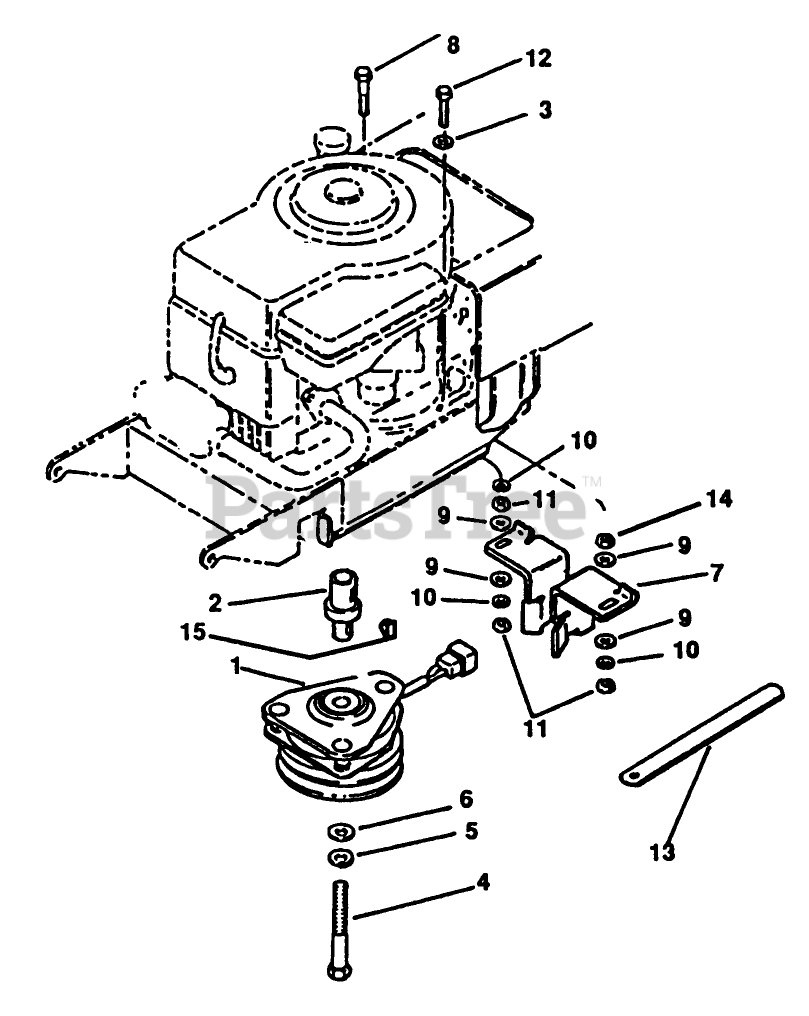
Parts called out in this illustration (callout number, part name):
1	CLUTCH-BRAKE ELECT
2	ADAPTER
4	SCREW-HEXHEAD CAP
15	KEY-HYPRO
